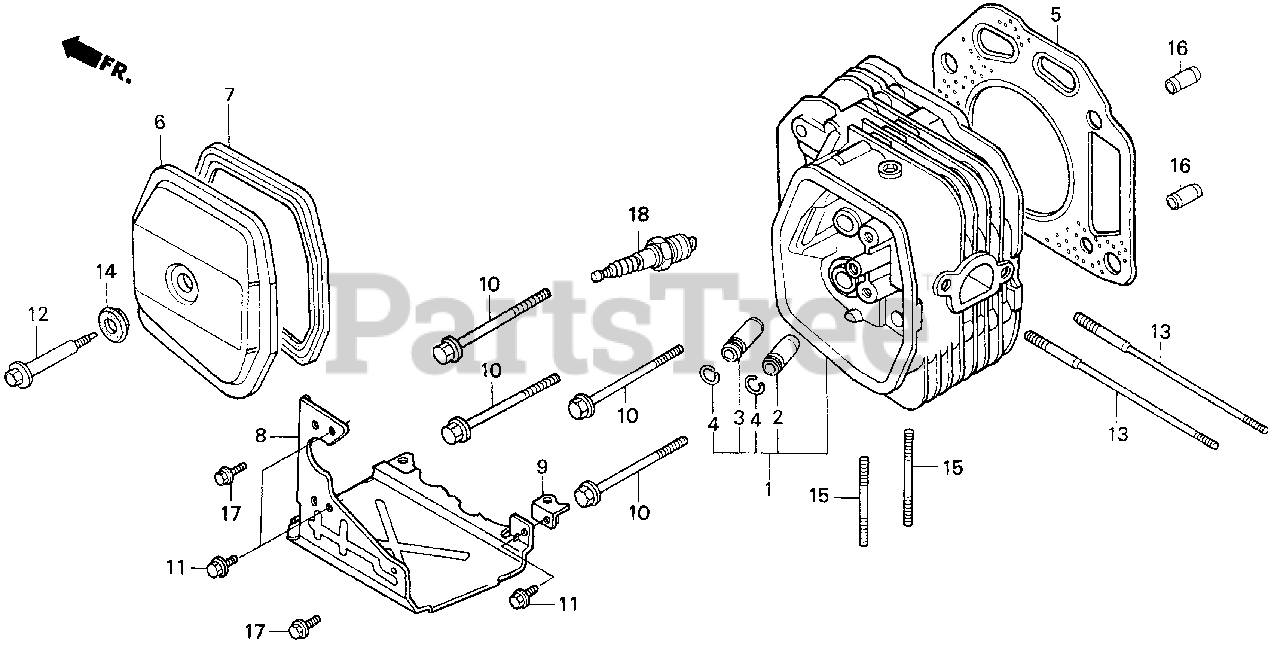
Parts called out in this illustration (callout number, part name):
1	CYLINDER HEAD
2	GUIDE, VALVE (OS)
3	GUIDE, EX. VALVE (OS)
4	CLIP, VALVE GUIDE
5	GASKET, CYLINDER HEAD
6	COVER, HEAD
7	GASKET, CYLINDER HEAD COVER
8	COVER (LOWER)
9	STAY, COVER (LOWER)
10	BOLT, FLANGE (10X85)
11	BOLT, FLANGE (6X12) (CT200)
12	BOLT, HEAD COVER
13	BOLT, STUD (8X131.5)
14	WASHER, HEAD COVER
15	BOLT, STUD (8X32)
16	PIN A, DOWEL (12X20)
18	SPARK PLUG (BPR5ES) (NGK)
18	SPARK PLUG (W16EPR-U) (DENSO)
